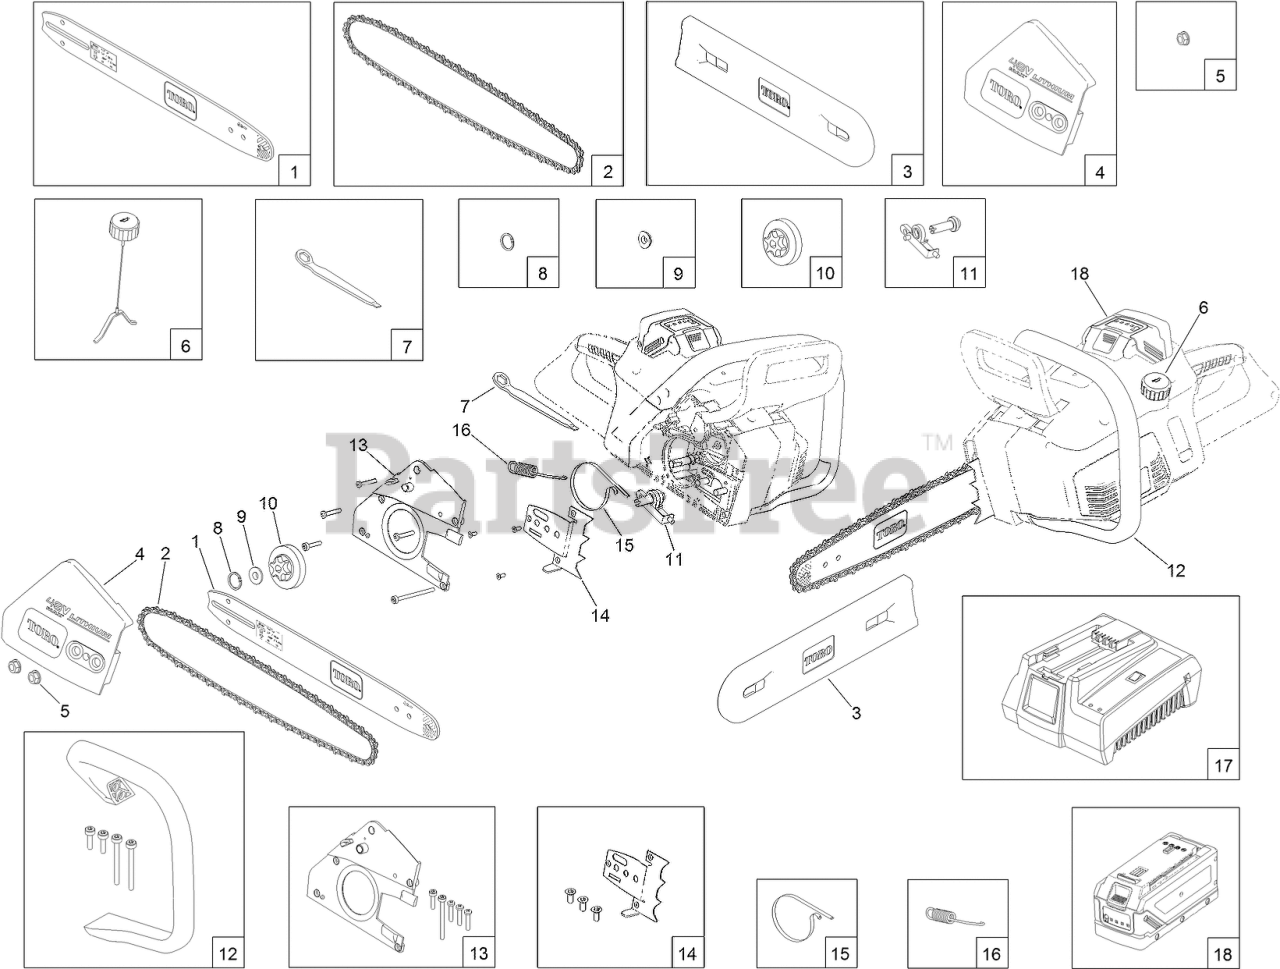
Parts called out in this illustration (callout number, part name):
1	BAR-REPLACEMENT
2	CHAIN-REPLACEMENT
3	SLEEVE-BAR
4	COVER-BAR/CHAIN
5	NUT-M8
6	OIL CAP ASM
7	WRENCH
8	SNAP-RING
9	SPACER
10	SPROCKET
11	BAR AND CHAIN ADJUSTER ASM
12	HANDLE ASM
13	INTERNAL COVER ASM
14	BUCKING TEETH BRACKET ASM
15	BRAKE-BAN
16	SPRING-LEVER, BRAKE
17	48V RAPID CHARGER
18	BATTERY PACK - EXTENDED, 48V (4AH)
